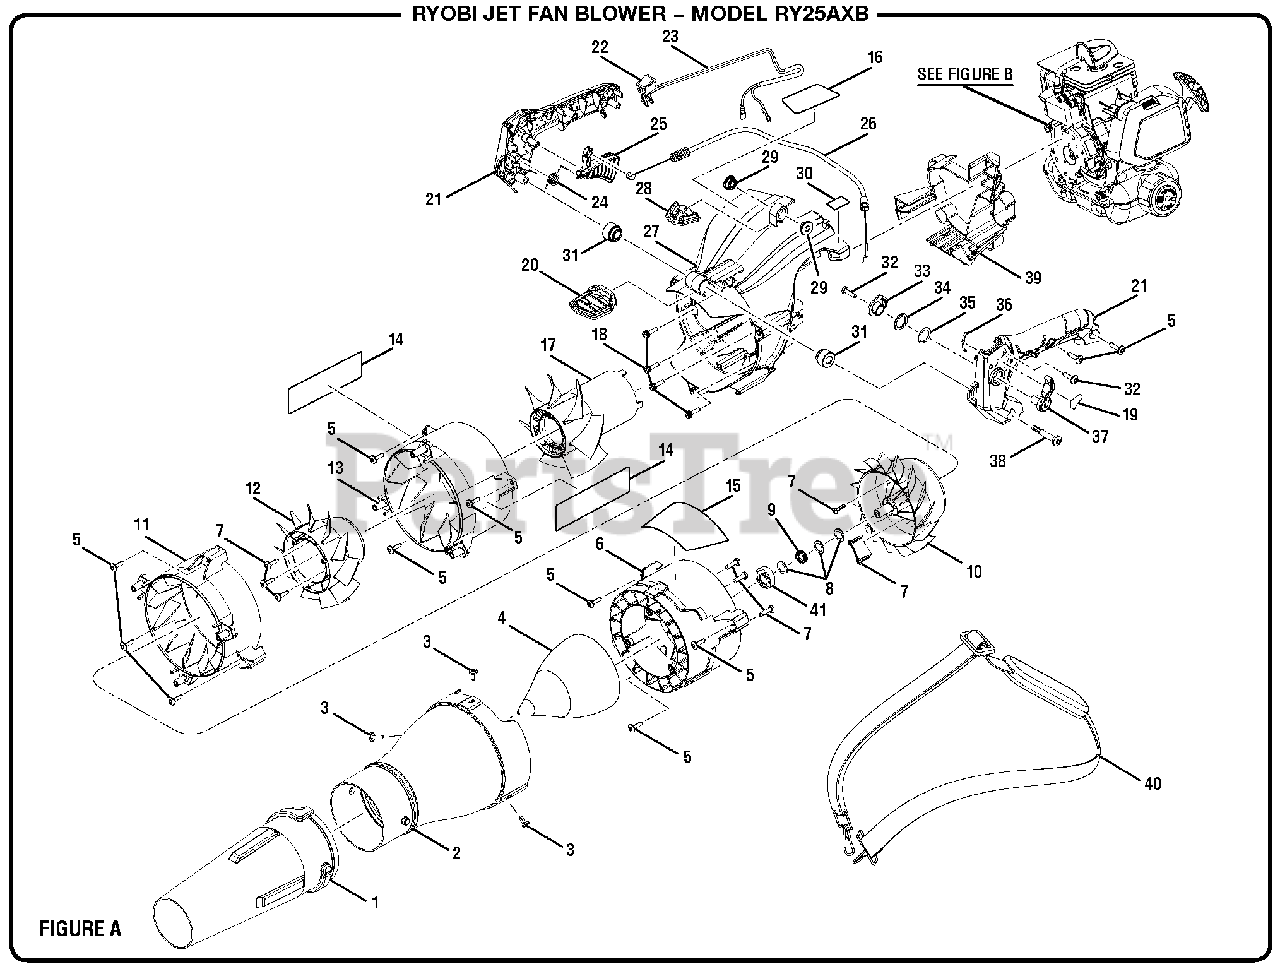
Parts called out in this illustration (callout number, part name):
1	Blower End Nozzle
2	Reducer Nozzle
3	Screw (10-14 x 13 mm, T25 Torx Truss Hd. T.F.)
4	Reducer Cone
5	Screw (10-14 x 19 mm., T25 Torx Truss Hd. T.F.)
6	Axial Stator w/Bearing Assembly Stage 3
7	Screw (M4 x 1.41 mm x 18 mm, T20 Torx Pan Hd. T.F)
8	Washer (OD18 x ID12.15 x 1.5t)
9	Wave Spring
10	Axial Fan (Stage 3)
11	Axial Stator (Stage 2)
12	Axial Fan (Stage 2)
13	Axial Stator (Stage 1)
14	Jet Fan Label
15	Logo Label (Full Crank, 2 cycle)
16	Warning Icon Label
17	Axial Fan (Stage 1)
18	Screw w/Washers (M5 x 20 mm, T20 Torx Pan Hd.)
19	Cruise Lever Position Label
20	Isolator Pad (Front Handle)
21	Handle Assembly
22	Stop Switch
23	Wiring Harness w/Fiber Sleeve
24	Throttle Spring
25	Throttle Trigger
26	Throttle Cable
27	Intake Housing
28	Isolator Pad (Rear Handle)
29	Bushing (Rear Isolator)
30	Primer Bulb Icon Label
31	Bushing (Front Isolator)
32	Screw (10-14 x 18 mm, T25 Torx Pan Hd. T.F.)
33	Throttle Actuator (Cruise Control)
34	Wave Washer
35	Washer (22.5OD x 16ID x 0.5t)
36	Detent Spring
37	Cruise Control Lever
38	Shoulder Screw (M5 x 40 mm, T25 Torx Truss Hd. T.F.)
39	Intake Guard
40	Shoulder Strap
41	Ball Bearing
